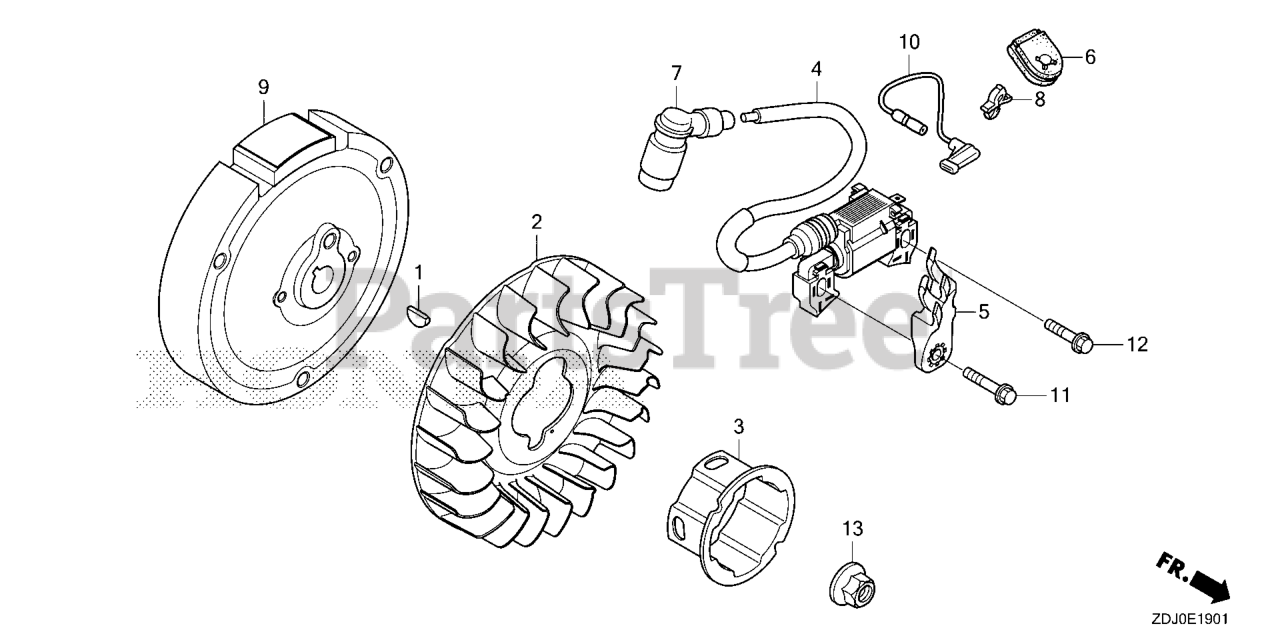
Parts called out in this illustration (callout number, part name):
1	KEY, SPECIAL WOODRUFF (25X18)
2	FAN, COOLING
3	PULLEY, STARTER
4	COIL ASSY., IGNITION
5	CLAMP, IGNITION WIRE
6	GROMMET, WIRE
11	BOLT (6X30) (CT200)
12	BOLT, FLANGE (6X25) Use up to Engine SN 2056819.
13	NUT, SPECIAL (14MM)
